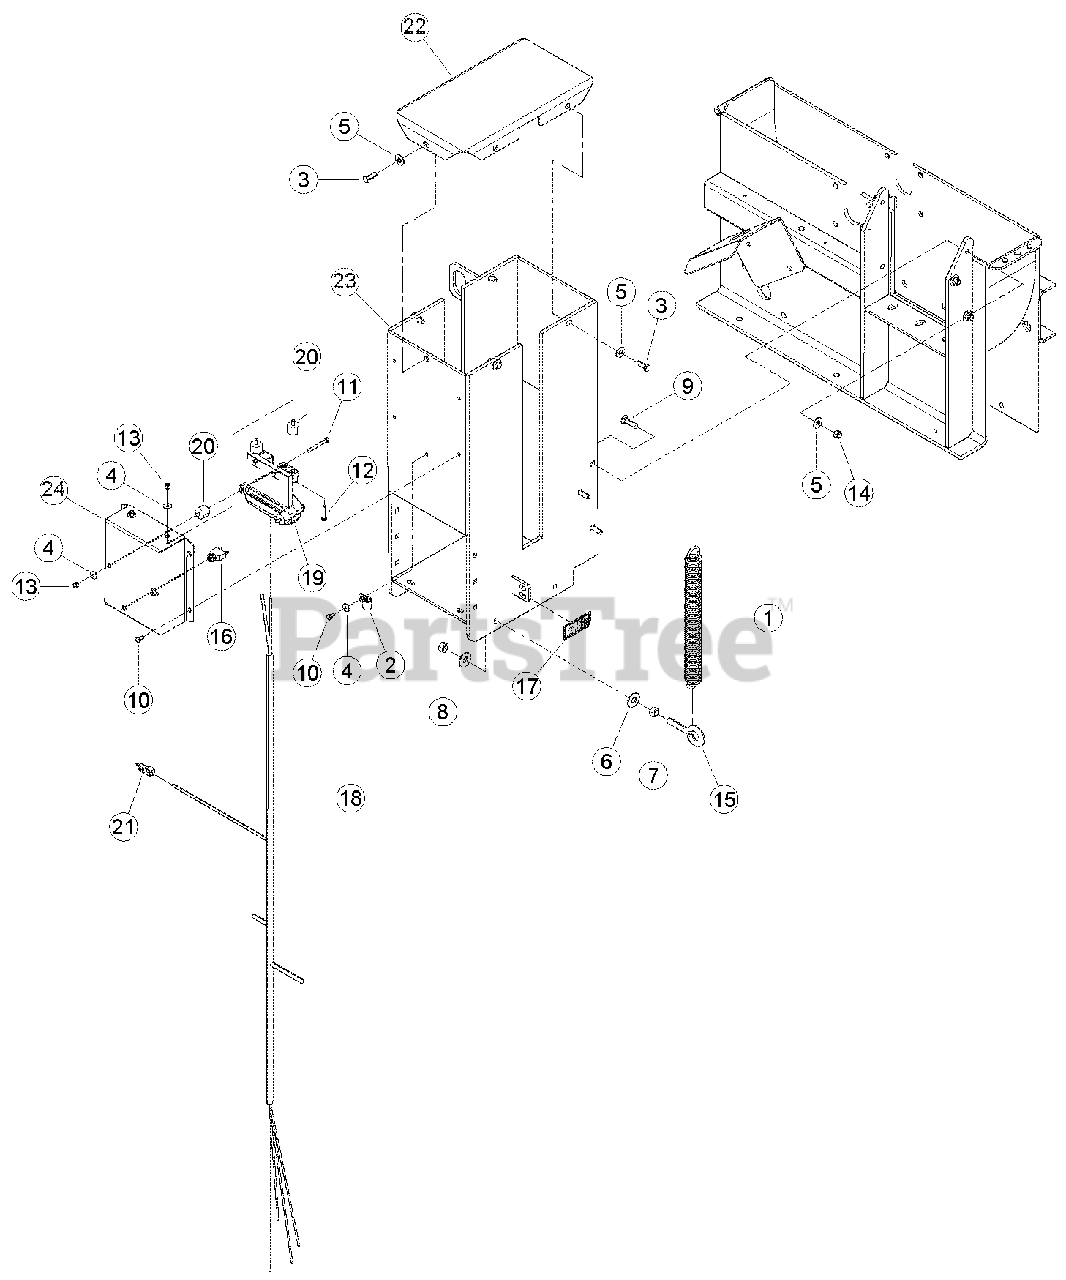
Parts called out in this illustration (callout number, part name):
1	SPRING, EXTENSION
2	CLAMP, 9/16" COATED
3	BOLT, 3/8 X 1 HEX HD GR5 ZP
4	WASHER, 1/4 FLAT ZP
5	WASHER, 3/8 FLAT ZP
6	WASHER, 1/2 FLAT ZP
7	NUT, 1/2 HEX NC ZP
8	NUT, 1/2 CENTERLOCK GRB ZP
9	BOLT, 3/8 X 1-1/2 CRG GR5 NC ZP
10	BOLT, 1/4 X 1/2 HEX HD GR5 ZP
11	BOLT, 1/4 X 2-1/4 HEX HD GR5 ZP
12	BOLT, 1/4 X 1-1/4 HEX HD GR5 ZP
13	NUT, 1/4 NE NYLOCK ZP
14	NUT, 3/8 NE NYLOCK ZP
15	EYEBOLT, 1/2 X 2 ZP
16	CIRCUIT BREAKER, 10 AMP RESETTABLE
17	DECAL, CRUSHING ISO
18	HARNESS, 9IN PTO - PLUS 1
19	CONTROLLER, PLUS 1 CHIPPER
20	BUMPER, 1" OD W/1/4" STUD
21	PLUG, JUMPER HARNESS
22	WELDMENT, TOP ROLLER COVER
23	WELDMENT, ROLLER SUPPORT
24	ENCLOSURE, PLUS 1 MOUNT
